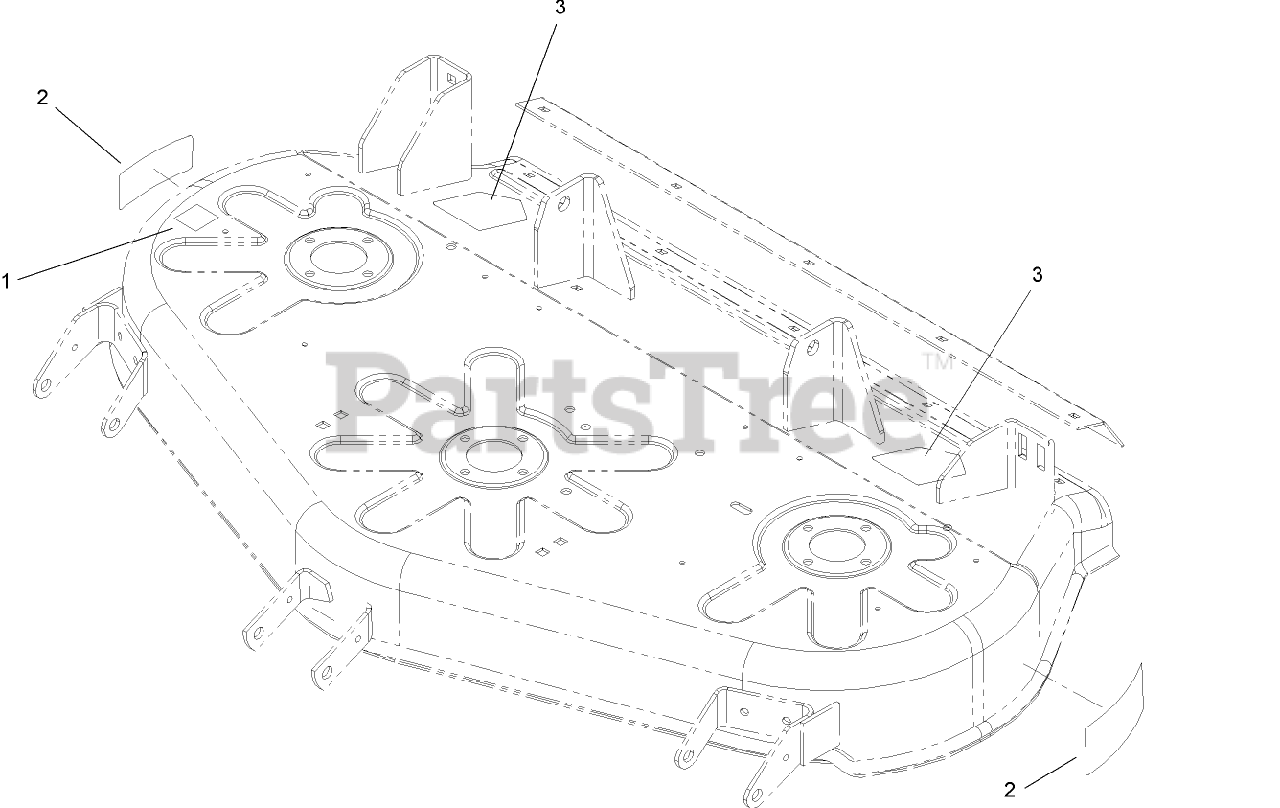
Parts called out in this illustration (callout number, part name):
1	DECAL-NOISE
2	DECAL-DANGER
3	DECAL-DANGER
